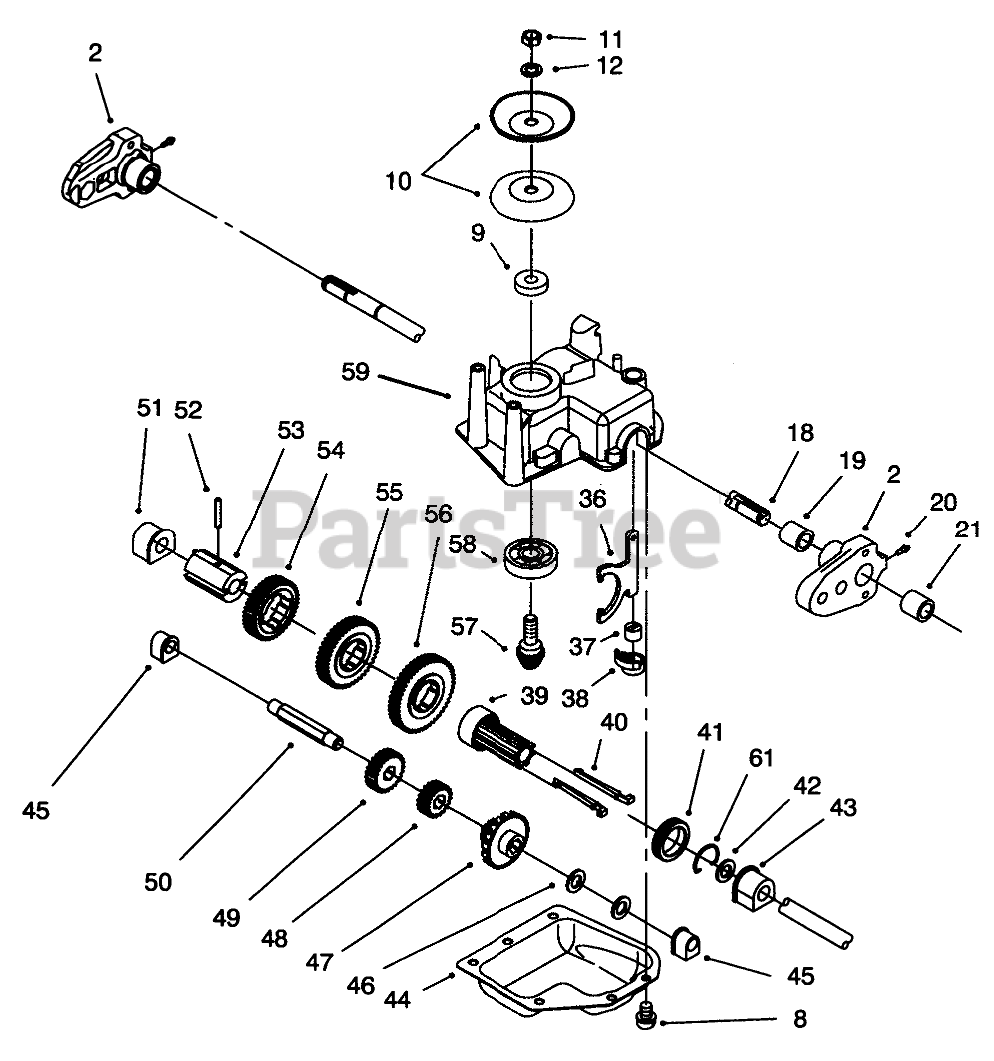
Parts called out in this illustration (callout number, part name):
2	Pivot Arm Assembly (Incl. Ref #19, 20, & 21)
8	SCREW-HWHTF
9	SPACER
10	Pulley Half
11	NUT-HEX
12	WASHER-FLAT
18	SHAFT-OUTPUT
19	BUSHING
20	FITTING-GREASE
21	BEARING-ROLLER
36	YOKE-SHIFT
37	BUSHING-YOKE
38	RETAINER-FORK, SHIFT
39	SLEEVE-KEY, SHIFT
40	KEY-SHIFT
41	COLLAR-SHIFT
42	WASHER-PLAIN
43	BUSHING-OUTPUT
44	Cover-Gearcase
45	BUSHING
46	WASHER-THRUST
47	Gear-Bevel
48	PINION-20T
49	PINION-25T
50	SHAFT-INTERMEDIATE
51	BUSHING
52	PIN-SPRING
53	SLEEVE-GEAR
54	GEAR-39T
55	GEAR-44T
56	GEAR-49T
57	Gear-Pinion
58	BEARING-BALL
59	CASE-GEAR, UPPER
61	CLIP-SPRING
